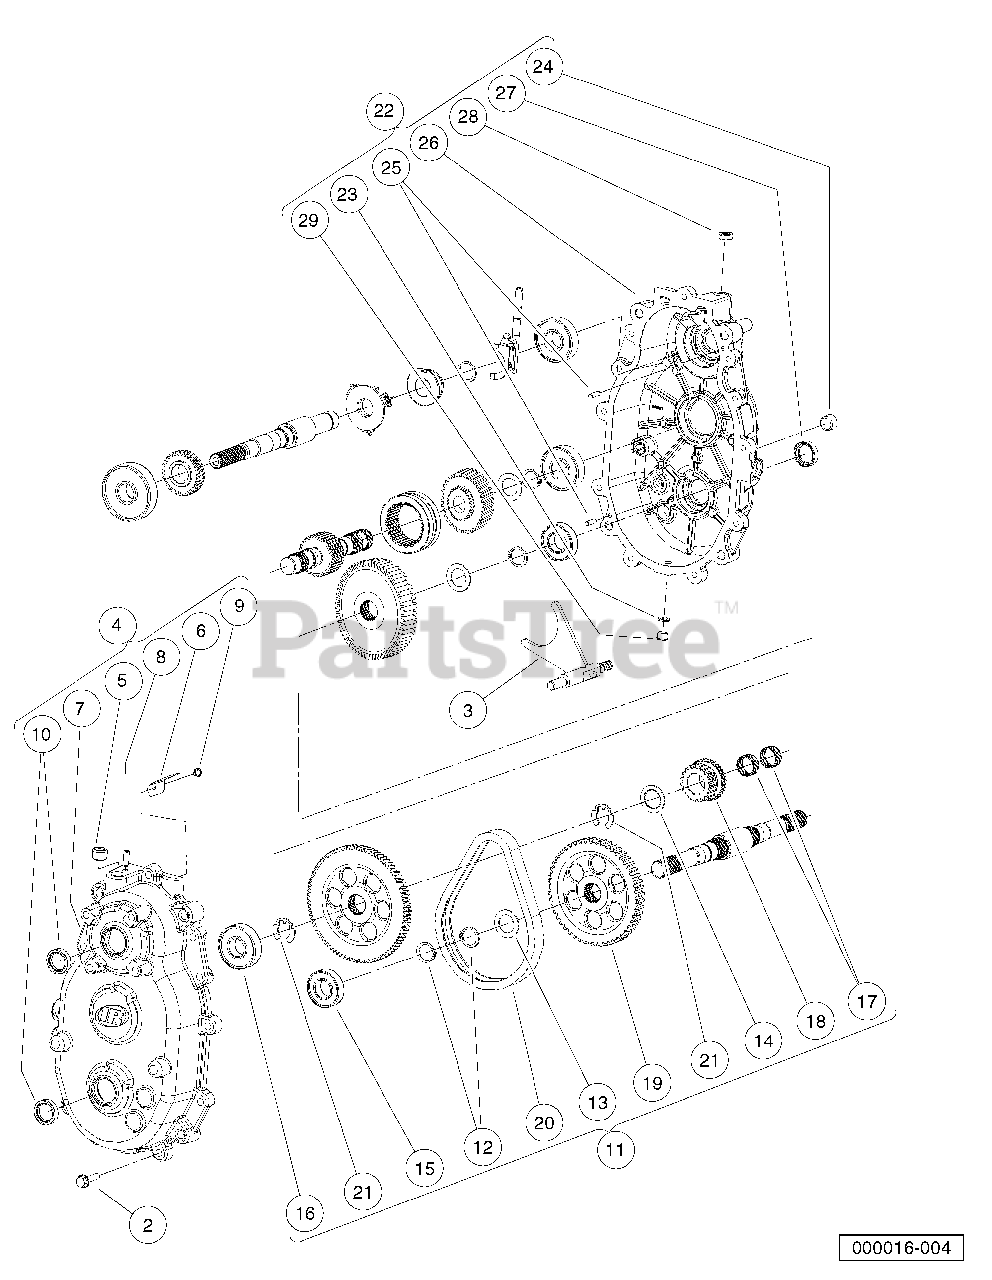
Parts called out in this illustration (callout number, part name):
1	Transmission, Parallel Shaft
2	Screw,hex Flange, M8 X 35
3	Fork, Transmission
4	Asm, Gear Case, Rear
5	Plug, Square Skt, 1/12-14, Ptf
6	Oil, Deflector
7	Gearcase, Rear
8	Vent, Trans
9	Screw, Tapping # 10-24 X .375
10	Seal, Triple, 25 X 35 X 7.8
11	Kit, Reverse Gear Repair
12	Ring, Retaining, Basic External
13	Washer, Thrust, 1.007 X .062
14	Washer, 26.231 X 39.167 X 1.57
15	Bearing, Ball
16	Bearing, Ball
17	Bearing, Needle
18	Sprocket, 19-Tooth
19	Sprocket, 51-Tooth
20	Chain, .375p, .75 Wide, 60ptch
21	Ring, Retaining, E-Ring
22	Asm, Case, Gear, Front
23	Washer, .625 X .382 X .60
24	Plug, Square Skt, 1/12-14, Ptf
25	Pin, Dowel, 6 X 20
26	Gearcase, Front
27	Seal, Triple, 25 X 35 X 7.8
28	Seal, Dual-Lip
29	Plug, 3/4-16
